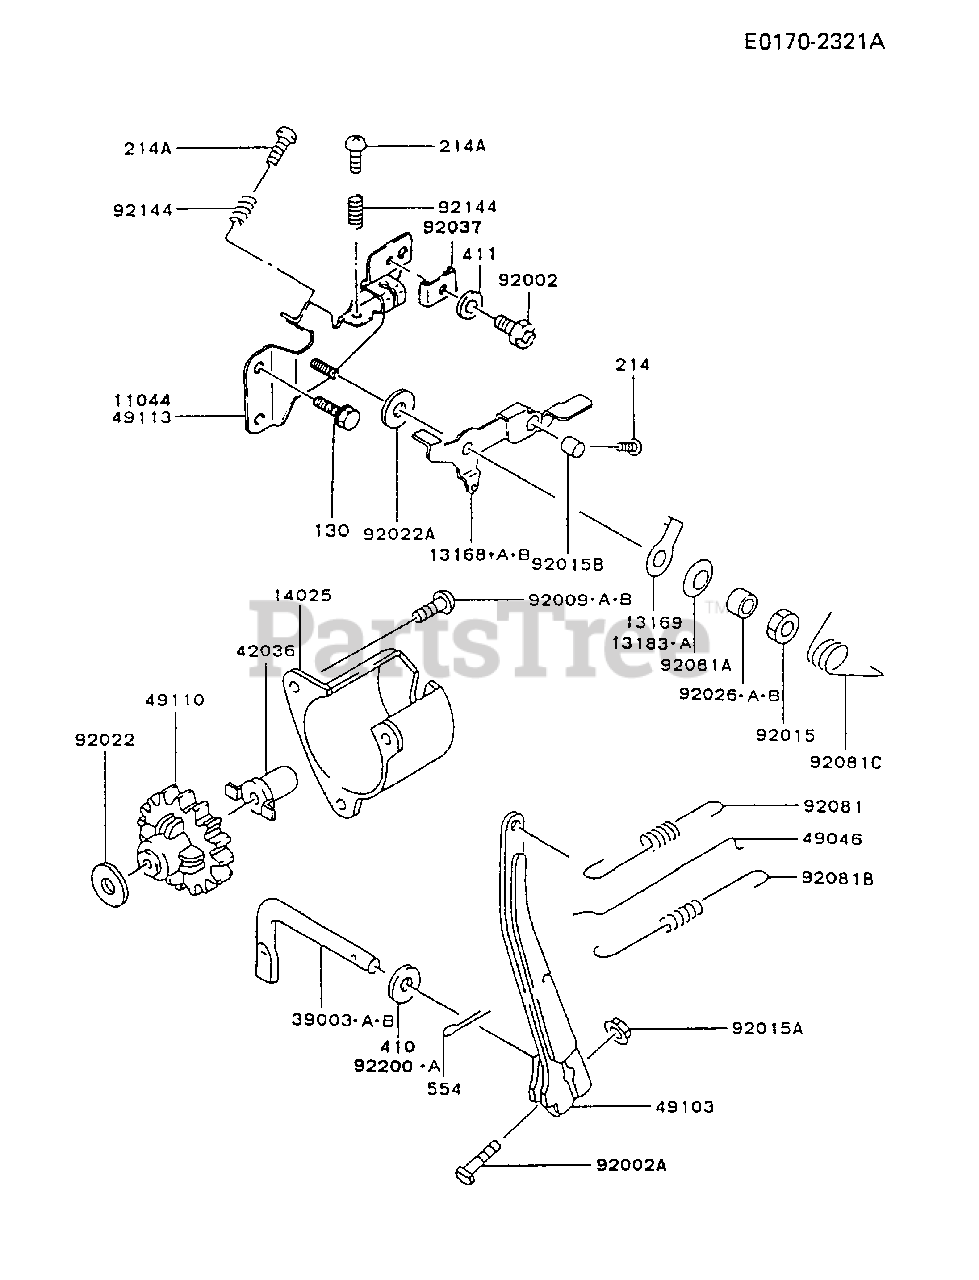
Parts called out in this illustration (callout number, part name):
130	BOLT-FLANGED
214	SCREW-PAN+-
214A	SCREW-PAN+-
411	WASHER-PLAIN
554	PIN-SNAP
